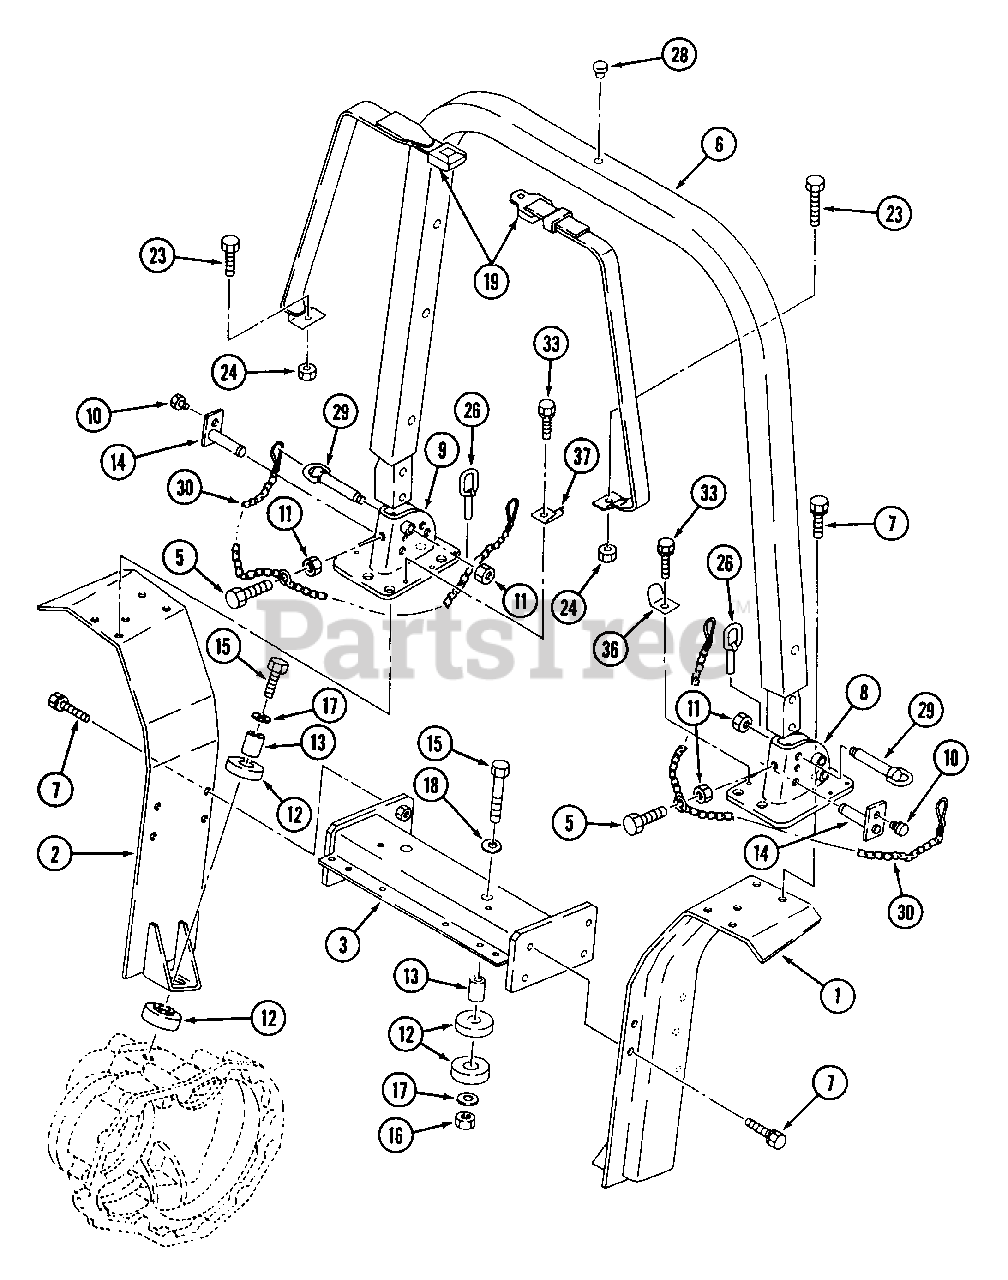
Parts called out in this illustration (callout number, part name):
8	Bracket, L.H.
9	Bracket, R.H.
12	Rubber, Cushion
19	Seat Belt Ass'y.
36	Hook, Seat Belt L.H.
37	Hook, Seat Belt R.H.
